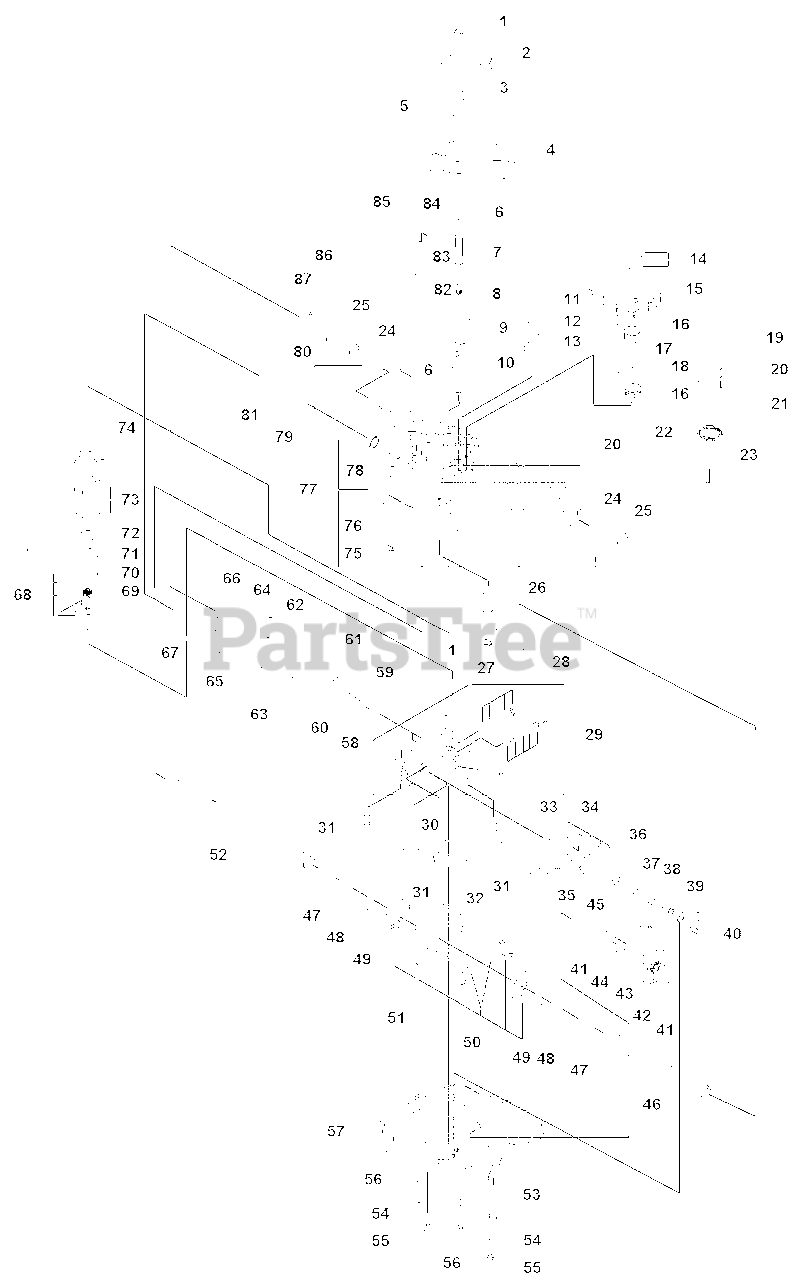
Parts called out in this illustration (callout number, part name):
1	SNAP RING
2	PULLEY
3	LOCK WASHER
4	FAN
5	SPLINE COLLAR
6	RING, "E"
7	PUMP SHAFT
8	SEAL
9	RING, Snap
10	BEARING
11	SEALING CAP
12	MAGNET
13	HOLDER, MAGNET
14	VENT VALVE
15	RESERVOIR TANK
16	MINIATURE CLAMP
17	SUPPORT
19	PIN
20	PIN
21	ARM, Brake
22	RETURN SPRING
23	O RING
24	BUSHING
25	SEAL
26	SHAFT, BRAKE
27	ACTUATOR, Brake
28	SHOE, BRAKE
29	CENTER CASE, Complete
31	BOLT
32	FILTER K55
33	WASHER
34	CYLINDER BLOCK
35	BEARING
36	HOUSING
37	SHAFT MOTOR
38	RING, Snap
39	BEARING
40	MOTOR GEAR
41	WASHER
42	REDUCTION GEAR
43	COLLAR, Final
44	FINAL PINION
45	REDUCTION SHAFT
46	AXLE SHAFT, LH
47	BUSHING
48	THRUST WASHER
49	RING
50	DIFF PINION, Kit
51	FINAL GEAR
52	AXLE SHAFT, RH
53	SCREW, Tapping
54	WASHER, Seal
55	SCREW, Cap
56	TAPPING SCREW
57	LOWER HOUSING
58	IDS SPRING
59	BALL, 3/16
60	IDS VALVE
61	SPRING, Torsion
62	CONTROL ARM
63	JERKY PLATE
64	COTTER PIN
65	PIN, SPRING
66	CONTROL SHAFT
67	FULCRUM, Eccentric
68	CYLINDER BLOCK
69	SPRING, Pump
70	THRUST PLATE
71	BEARING
72	THRUST PLATE
73	SWASH PLATE COMPLETE
74	THRUST METAL
76	SPRING
77	UPPER HOUSING
78	OIL SEAL
79	O RING
80	WASHER
81	NUT
82	SHAFT, Bypass
83	O RING
84	ROLL PIN
85	LEVER, Bypass
86	CONTROL LEVER
87	PIN, Roll
